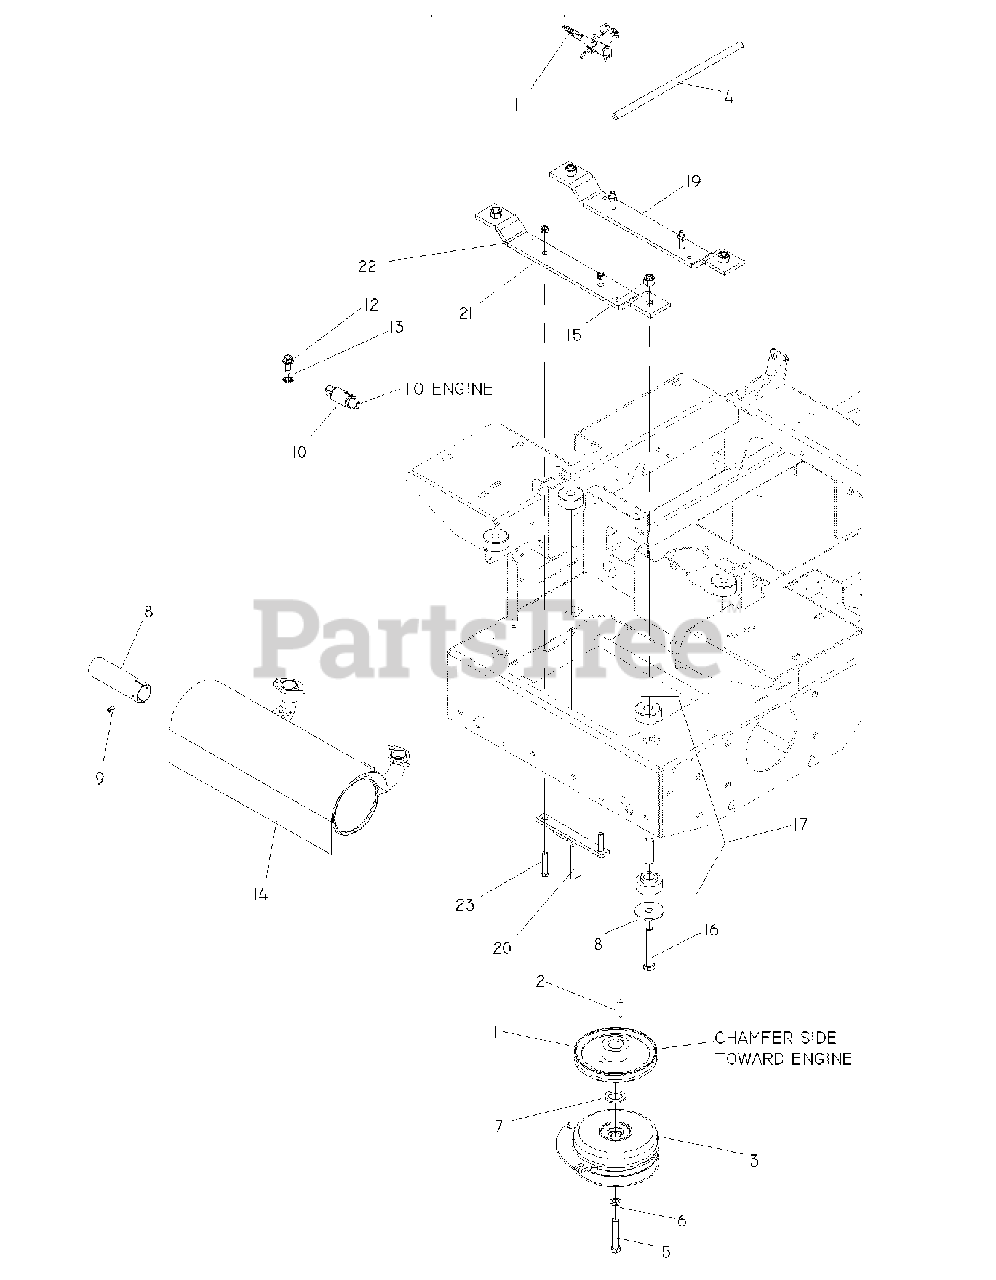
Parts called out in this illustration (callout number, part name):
2	KEY, 1/4 SQ X 1 1/4
3	CLUTCH-200 FT LB(RPLS 5218-102
4	FUEL LINE 13"
5	BOLT 7/16F X 2 1/2
6	WASHER 7/16 LOCK
7	BUSHING, 10GA MACHINERY
8	TUBE, EXTENSION, MUFFLER
9	SCR #8 X 1/2 PHIL HD DRILL BLK
10	OIL DRAIN FITTING
11	CHOKE CABLE
12	BOLT 3/8-16 X 1.0
13	WASHER 3/8 EXT STAR ZD
14	MUFFLER
15	NUT 1/2-13 HEX NYLOC ZD
16	HCS 1/2C X 3 1/4
17	ISOLATORS
18	ISOLATOR WASHER
19	ENGINE MOUNT
20	CLUTCH TIE DOWN
21	STRAP, ISO, REAR
22	NUT 5/16C CENTERLOCK
23	HCS 5/16-18 X 1-3/4 SERATED
